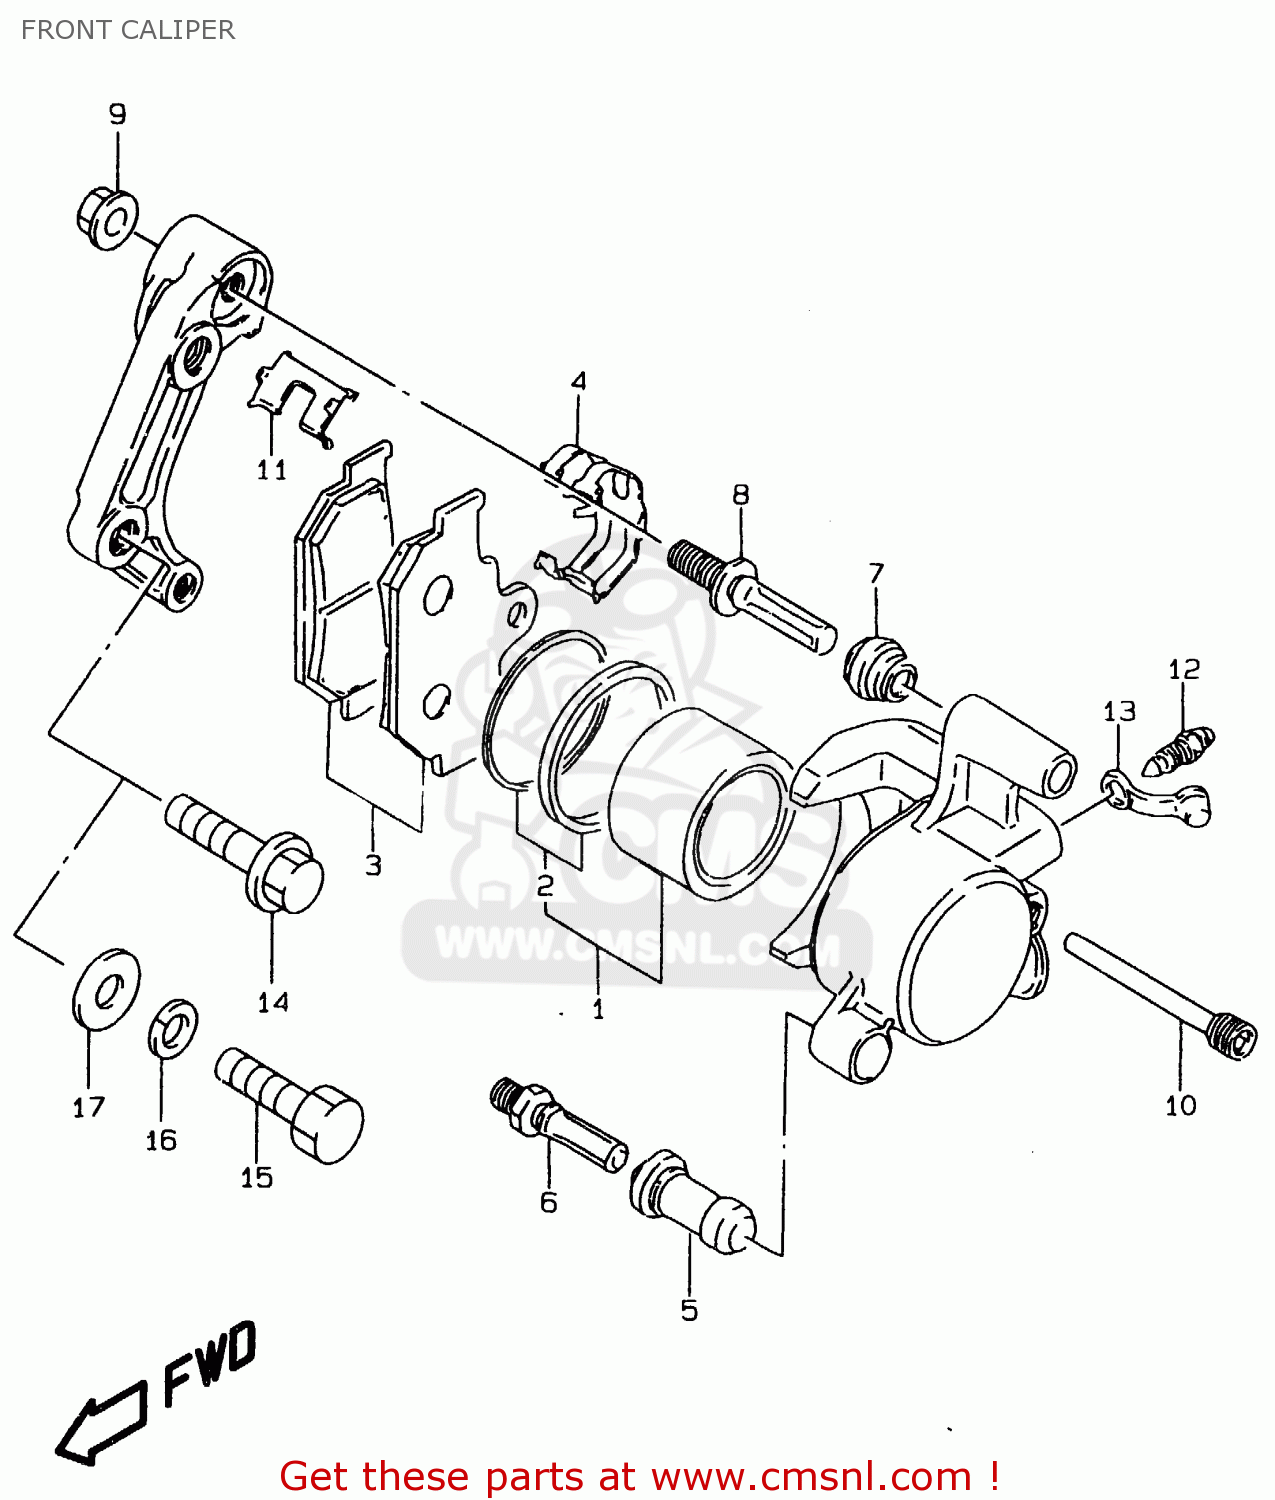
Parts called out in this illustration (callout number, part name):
1	PISTON SET
2	SEAL SET,PISTON
3	PAD SET (NAS)
4	SPRING
5	BOOT
6	BOLT
7	BOOT
8	PIN,SLIDE
9	NUT,SLIDE PIN
10	PIN,HANGER
11	RETAINER
12	BLEEDER
13	CAP,BLEEDER
14	BOLT 10X38
15	BOLT(10X38)
16	WASHER,LOCK
17	WASHER
